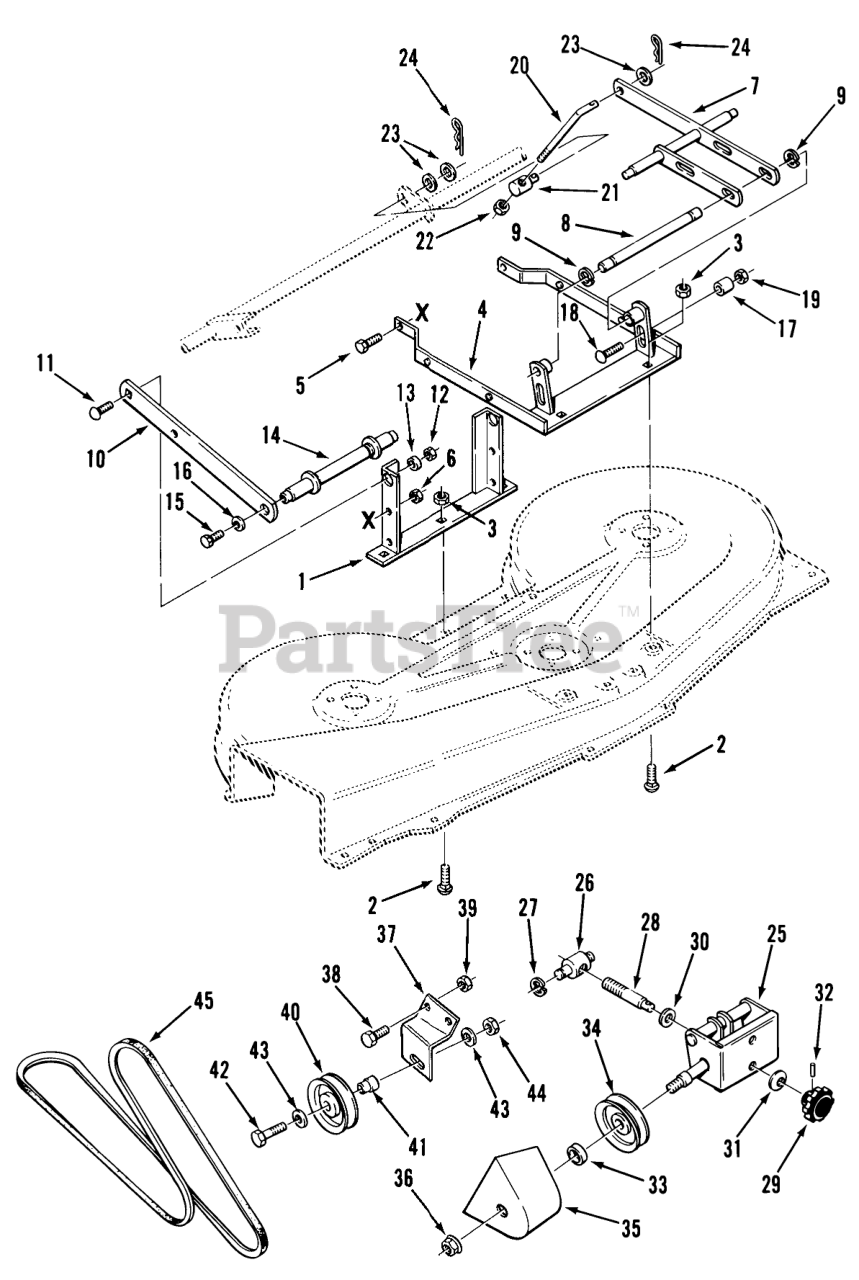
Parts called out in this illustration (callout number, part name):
1	ASSY REAR SUPPORT
2	CARRIAGE BOLT
3	Eslok Nut
4	ASSY FRONT HANGER BR
5	BOLT
6	Nut
7	Leveler Bar
8	SHAFT-FRONT
9	E-Ring
10	Draft Bar
11	Bolt
12	LOCKNUT-FLANGE
13	SPACER
14	Hitch Shaft
15	Bolt
16	Washer
17	SPACER-BEARING
18	CARRIAGE BOLT -4
19	Nut
20	ROD-LEVEL ADJUST
21	TRUNION
22	Nut
23	Washer
24	Hairpin Cotter
25	ASSY FRONT SUPPORT
26	TRUNNION-DOUBLE
27	RING-RETAINING
28	ROD ADJ
29	KNOB-ADJUSTMENT
30	Washer
31	WASHER-SPRING
32	PIN-ROLL
33	SPACER
34	Pulley-V
35	Belt Cover
36	Nut 3/4-16 MF
37	BRACKET FLAT IDLER
38	BOLT
39	Nut
40	PULLEY-FLAT IDLER
41	SPACER
42	Bolt
43	Washer
44	NUT
45	Mower Drive Belt
